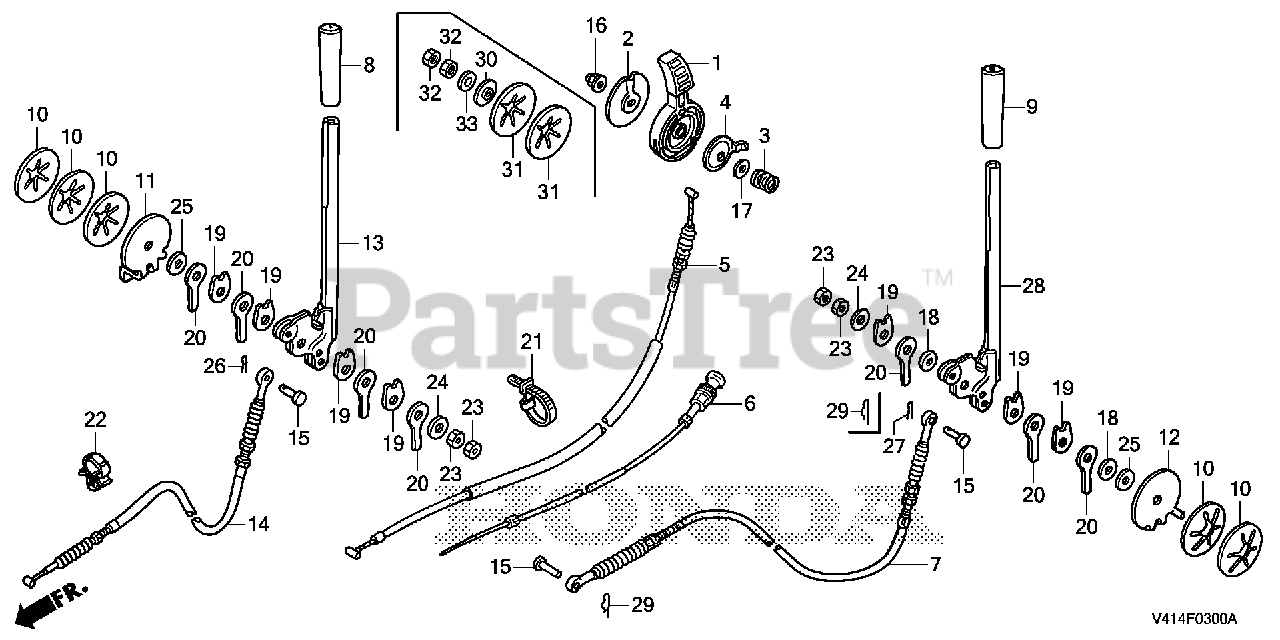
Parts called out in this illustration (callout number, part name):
1	LEVER, THROTTLE
2	PLATE, THROTTLE LEVER
3	SPRING, THROTTLE LEVER
4	SEAT, SPRING
5	CABLE, THROTTLE
6	CABLE, CHOKE
7	CABLE, CHANGE
8	GRIP, CHANGE LEVER
9	GRIP, CHANGE LEVER (ORANGE)
10	SPRING, ADJUSTING ARM
11	PLATE, R. STOPPER
12	PLATE, L. STOPPER
13	LEVER, CHANGE
14	CABLE, CHUTE GUIDE
15	PIN, CONTROL BOX SETTING
16	NUT, SELF-LOCK (6MM)
17	WASHER (10.2MM)
18	WASHER, LOCK
19	WASHER, FRICTION
20	WASHER, FRICTION SETTING
21	BAND, WIRE (165MM) (BLACK)
22	CLAMP, CABLE
23	NUT, HEX. (8MM)
24	WASHER, PLAIN (8MM)
25	WASHER, PLAIN (8MM)
26	PIN, COTTER (2.0X12)
27	PIN, COTTER (2.0X12)
28	LEVER, CHANGE
29	PIN, LOCK (6MM)
30	WASHER, RR. TURN SIGNAL
31	SPRING, ADJUSTING ARM
32	NUT, HEX. (6MM)
33	WASHER, PLAIN (6MM)
